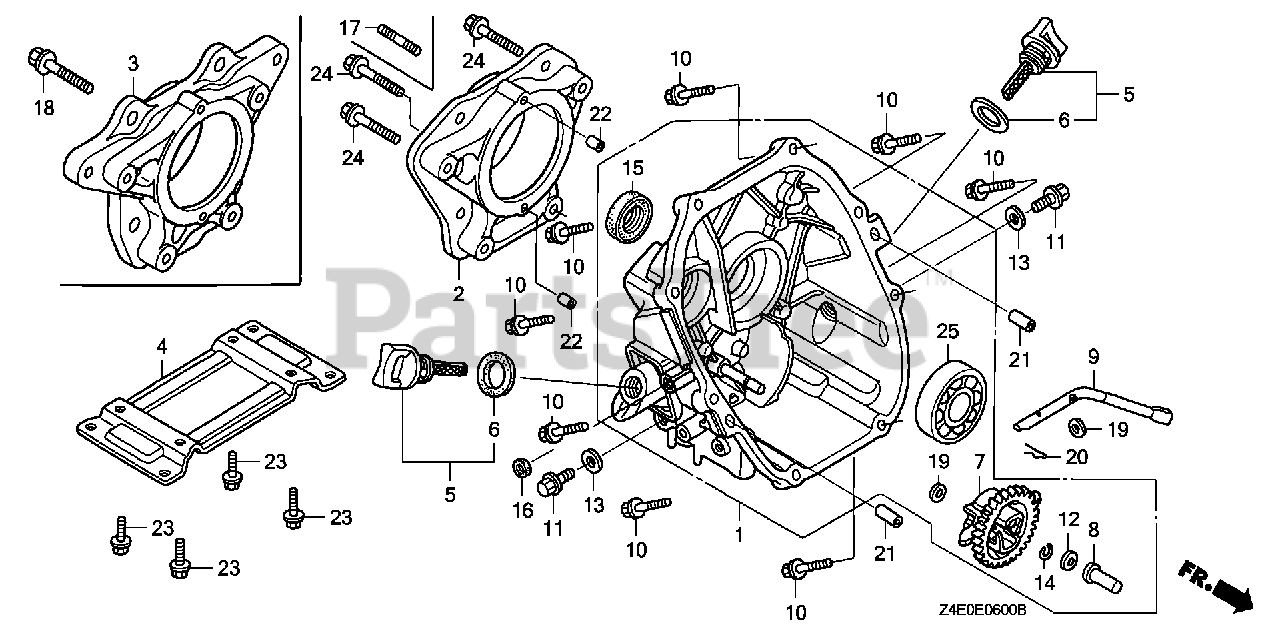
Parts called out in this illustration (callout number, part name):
1	COVER ASSY., CRANKCASE
4	BED, ENGINE
5	CAP ASSY., OIL FILLER
6	GASKET, OIL FILLER CAP
7	GOVERNOR ASSY.
8	SLIDER, GOVERNOR
9	SHAFT, GOVERNOR ARM
10	BOLT, FLANGE (6X25) Use up to Engine SN 2056819.
11	BOLT, DRAIN PLUG
12	WASHER, THRUST (6MM)
13	WASHER, DRAIN PLUG (10.2MM)
14	CLIP, GOVERNOR HOLDER
15	OIL SEAL (20X32X6)
19	WASHER, PLAIN (6MM)
20	PIN, LOCK (8MM)
21	PIN, DOWEL (8X20)
23	BOLT, FLANGE (8X25)
25	BEARING, RADIAL BALL (6204)
